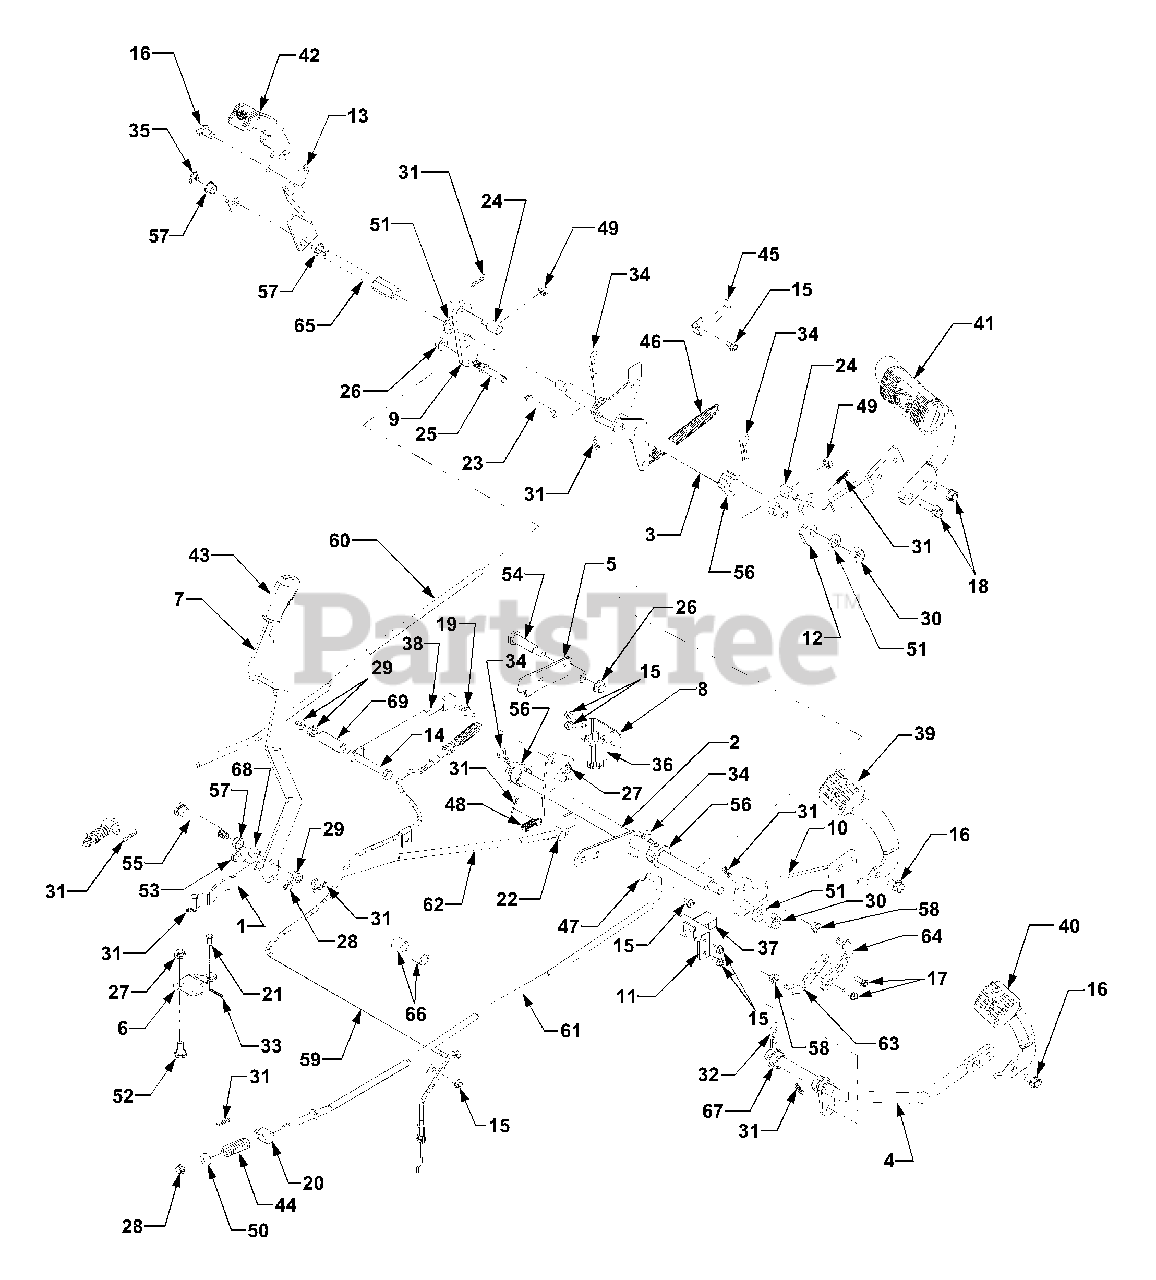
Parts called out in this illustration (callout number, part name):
1	Link, Hi-Lo
2	Shaft Assembly, Pedal
3	Shaft Assembly, Brake
4	Shaft Assembly, Reverse
5	Link Assembly, Parking Brake
6	Link, Hi-Lo Pivot
9	Lever, Brake
13	Bracket, Pedal Brace
14	Screw, Hex Cap 3/8-16 x 3.0 GR8
15	Screw, Hex Wash Hd Tapp 1/4-20 x .5
16	Screw, Hex Wash Hd Tapp 3/8-16 x .75
17	Screw, Hex Wash Hd Tapp 1/4-20 x .75
18	Screw, Hex Wash Hd Tapp 3/8-16 x 1.25
19	Stud, Cylinder, 5/16-18
20	Ferrule, Brake
21	Pin, Clevis, .25 x .5
22	Ferrule, 3/8-24 x .37
23	Pin, Clevis, 3/8 x 2.015
24	Ferrule, 3/8 - 24 x .375
25	Pin, 3/8-16: 3/8 x 2.43
26	Nut, Hex Flange Lock, 3/8-16
27	Nut, Hex Flange Lock, 5/16-18
28	Nut, Hex Flange Lock, 1/4-20
29	Nut, Hex Lock, 3/8-16
30	Nut, Hex Insert Lock, 1/2-20
31	Pin, Internal Cotter
32	Pin, Internal Cotter
33	Pin, Cotter, 3/32 x .750
34	Pin, Internal Cotter
35	E-Ring, .5 Dia
36	Switch, Plunger (Brake)
37	Switch, Plunger (Reverse)
38	Cylinder, Damper
39	Pedal, Forward
40	Pedal, Reverse
41	Pedal, Brake
42	Pedal, Diff. Lock
43	Grip, Handle
44	Spring, Compression
45	Spring, Switch Actuator
46	Spring, Extension, .62 x 6.12
47	Spring, Rev/No Cut
48	Spring, Extension, 3/8 x 1.44
49	Nut, Hex Jam, 3/8-24
50	Washer, Flat, .28 x .74 x .063
51	Washer, Flat, .53 x .1.06 x .134
52	Screw, Shoulder, .435 x 1.78
53	Screw, Shoulder, ..375 x .181
54	Screw, Shoulder, .498 x 1.635
55	Screw, Shoulder .498 x 3.245: 3/8-16
56	Bearing, Hex Flange, .752 ID
57	Bearing, Nylon. .50 ID x .341
58	Bearing, Flange, .375 x .58 x .25
59	Cable, Diff Lock
60	Rod, Brake, LH
61	Rod, Brake, RH
62	Rod, Hydro Control
63	Rod, Rear Connecting
64	Rod, Front Connecting
65	Shaft, Diff. Lock
66	Spacer, .508 x .75 x .68
67	Bearing, Hex Flange, .629 ID
68	Spacer, .50 ID x .62 x .37
69	Spacer, .39 x .625 x 1.74
